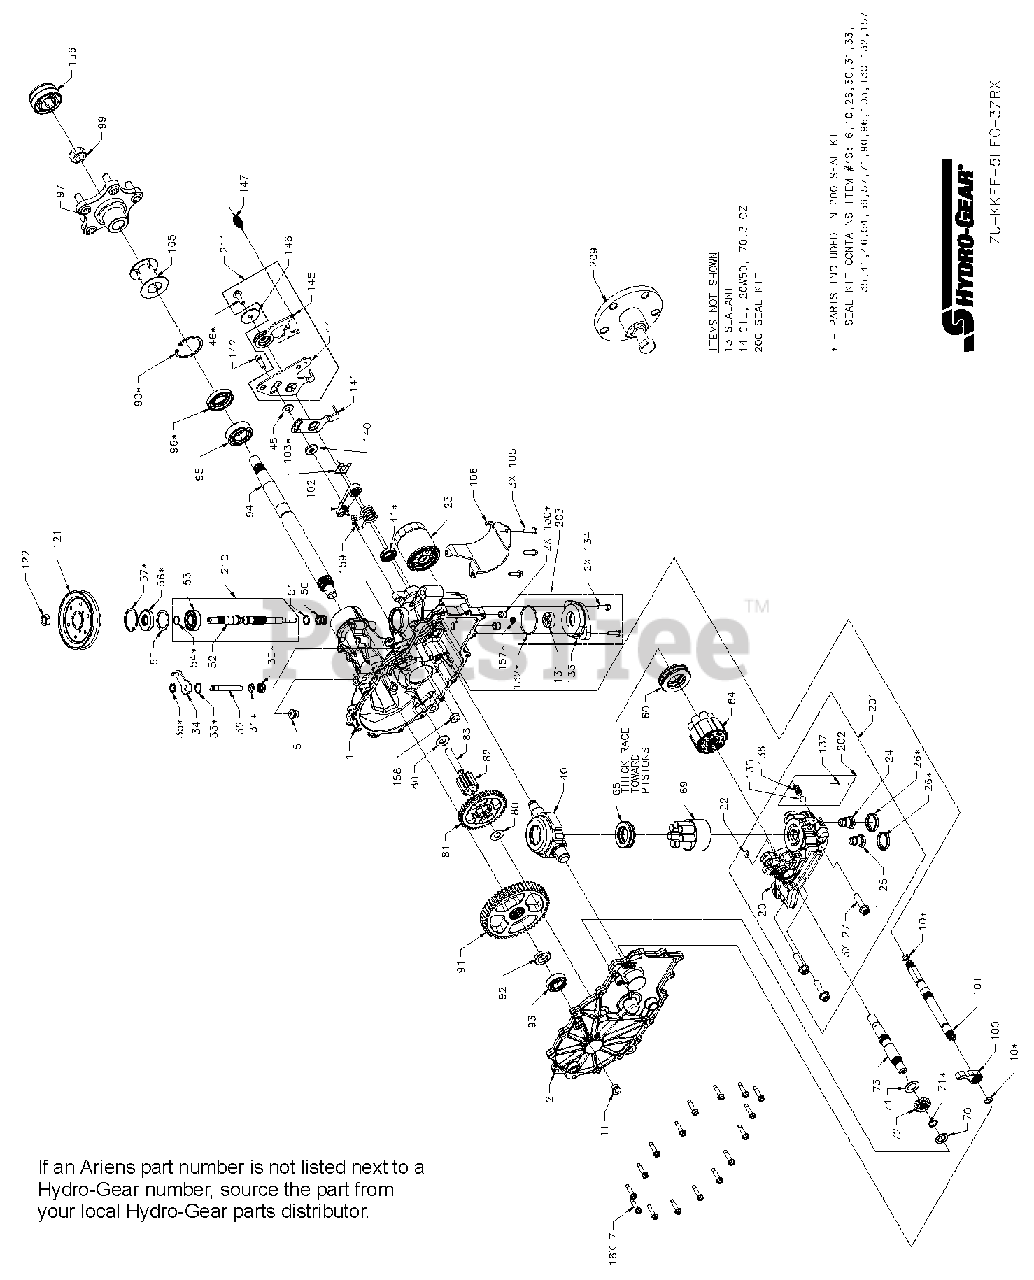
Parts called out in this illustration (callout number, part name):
13	SEALANT
23	FILTER, OIL
30	SEAL, LIP .375 x .75 x .25
31	RING, RET .375 EXTRNL
35	RING, RTNG .375 EXT
40	TRUNNION, SWASHPLATE
41	SEAL, LIP 12 x 32 x 7
46	TWHCS 5/16-24 x 1.00 (PATCH)
51	WASHER-FLAT .59 x .79 x .04
55	WASHER 1.23 x 1.56 x .04
56	SEAL, LIP 17 x 40 x 7
57	RING, RETAINING
80	WASHER .5 x 1.0 x .03
95	BRG, BALL 25.4 x 52 x 15
96	SEAL, LIP 1.000 x 2.049 x .375
99	NUT, HEX LOCK 3/4-16
122	NUT,HEX JAM 1/2-20 W/ PATCH
132	O-RING, -137, 0.103 x 2.050
146	WASHER, .343 x 1.500 x .062
147	SPRING, EXTNSN RTN-34LBS
